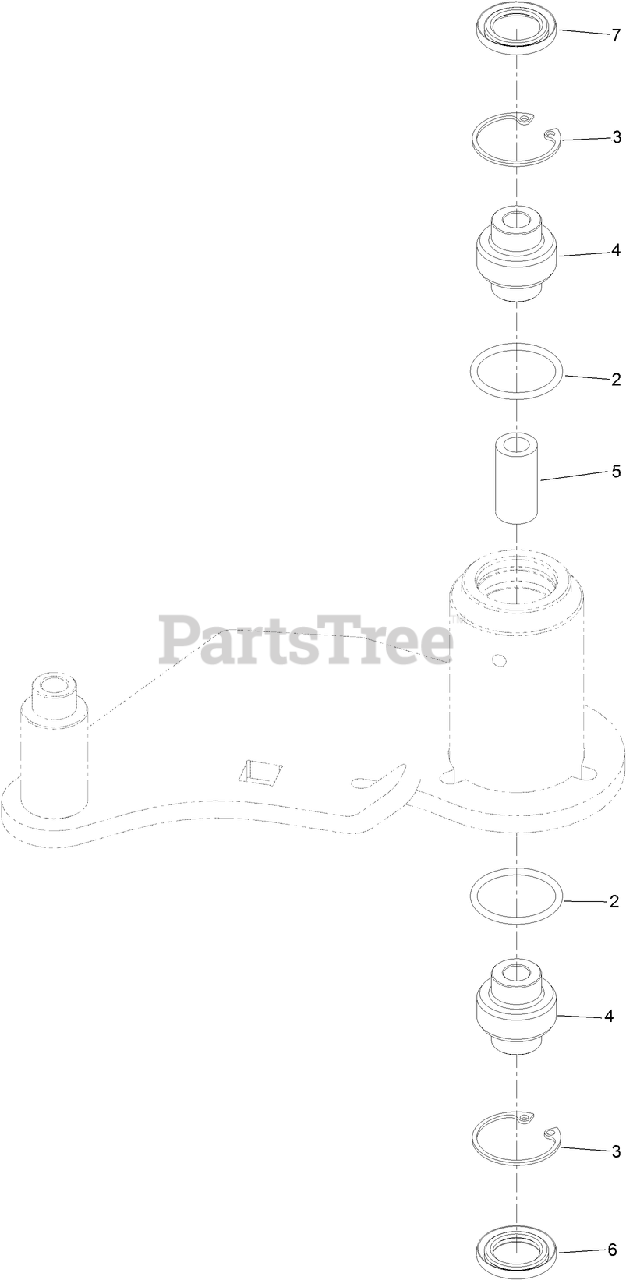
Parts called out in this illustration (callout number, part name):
2	O-RING
3	RING-SNAP
4	BEARING-SPHERICAL
5	SPACER
6	Seal-Lip, Double
7	SEAL-LIP, SINGLE
